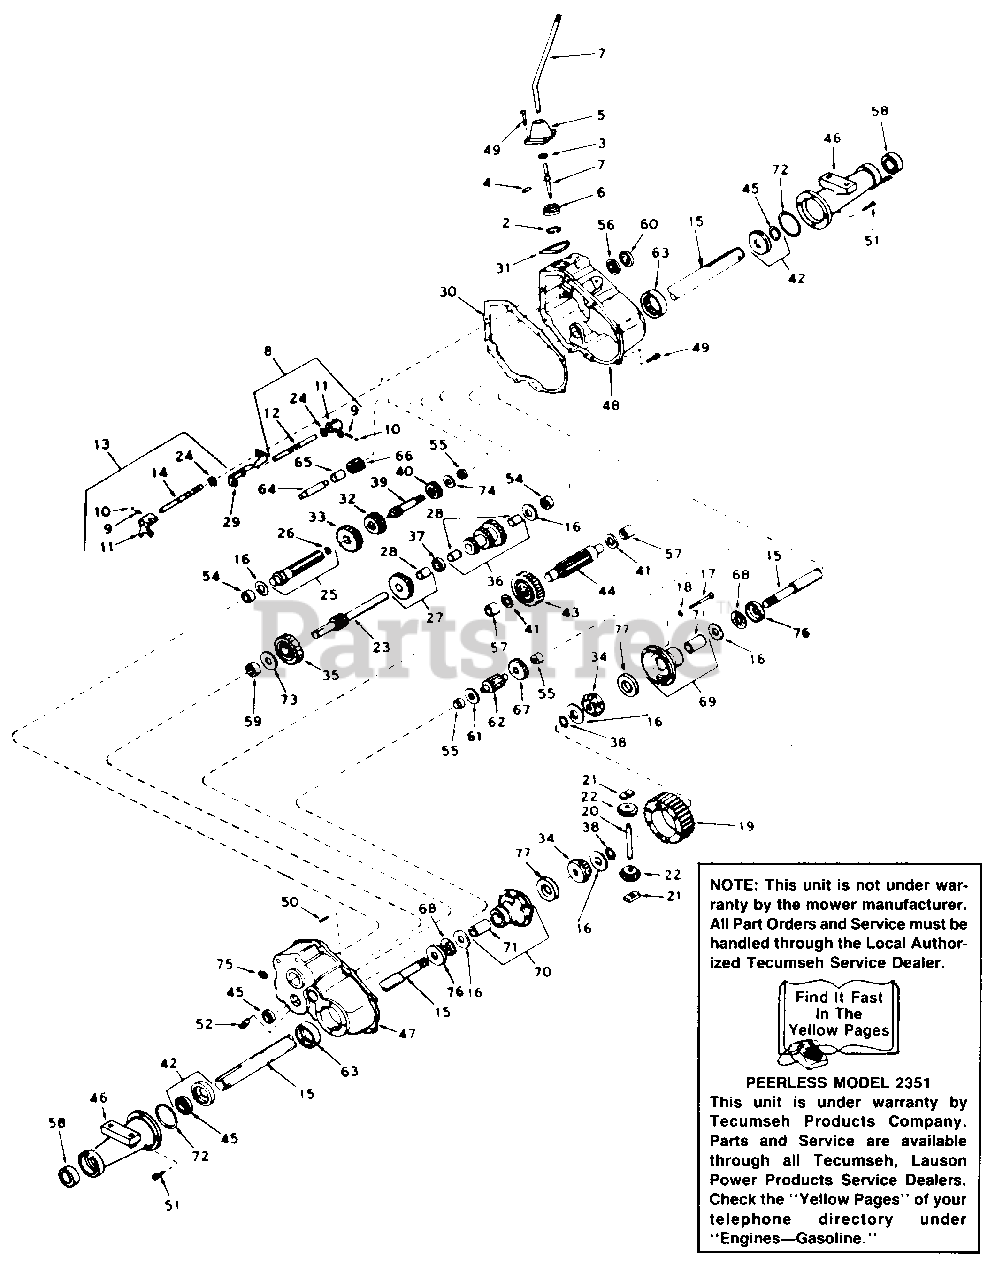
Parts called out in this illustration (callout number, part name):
2	Ring: Snap
3	Ring: Quad
4	Pin: Roll
5	Housing: Shift Lever
6	Keeper: Shift Lever
7	Lever: Shift
8	Rod Ass'y.: Shift
9	Spring
10	Ball: Steel
11	Fork: Shifter
12	Rod: Shifter
13	Rod Ass'y.: Shift
14	Rod: Shifter
15	Axle (18-11/32" Long)
16	Washer: Thrust
17	Scr.: Hex Hd.: 1/4-20 x 2'/2
18	Lock Washer: 114"
19	Gear: Ring
20	Pin: Drive
21	Block: Drive
22	Pinion: Bevel
23	Shaft and Gear: Brake
24	Ring: Snap
25	Shaft and Bearing Ass'y.:Pinion
26	Bearing: Needle
27	Gear Cluster Ass'y.
28	Bushing
29	Stop: Shifter
30	Gasket: Case and Cover
31	Gasket: Shifter Lever Housing
32	Gear: Shifting
33	Gear: Shifting
34	Gear: Bevel
35	Gear: Idler
36	Gear Cluster Ass'y.
37	Spacer
38	Ring: Snap
39	Shaft: Input
40	Spur Gear: Input Shaft
41	Washer: Thrust
42	Seal and Retainer Ass'y.:Oil
43	Gear: Output
44	Pinion: Output
45	Seal: Oil
46	Housing: Axle
47	Cover Ass'y.: Transaxle
48	Case Ass'y.: Transaxle
49	Screw: Socket Hd.: 1/4-20 x 314
50	Pin: Dowel
51	Screw: Hex Hd. Sems: 5/16-18 x 1
52	Plug: Magnetic Drain
54	Bearing: Needle
55	Bearing: Needle
56	Bearing: Ball
57	Bearing: Needle
58	Bearing: Ball
59	Bearing: Needle
60	Seal: Oil
61	Washer
62	Shaft and Pinion
63	Bearing: Needle
64	Shaft: Reverse Idler
65	Spacer: Reverse Idler
66	Idler: Reverse
67	Spur Gear (22 Teeth)
68	Bearing: Thrust
69	Carrier Ass'y.: Differential
70	Carrier Ass'y: Differential
71	Bushing
72	"O" Ring
73	Washer: Thrust
74	Washer: Thrust
75	Plug: Pipe
76	Race: Thrust
77	Washer
